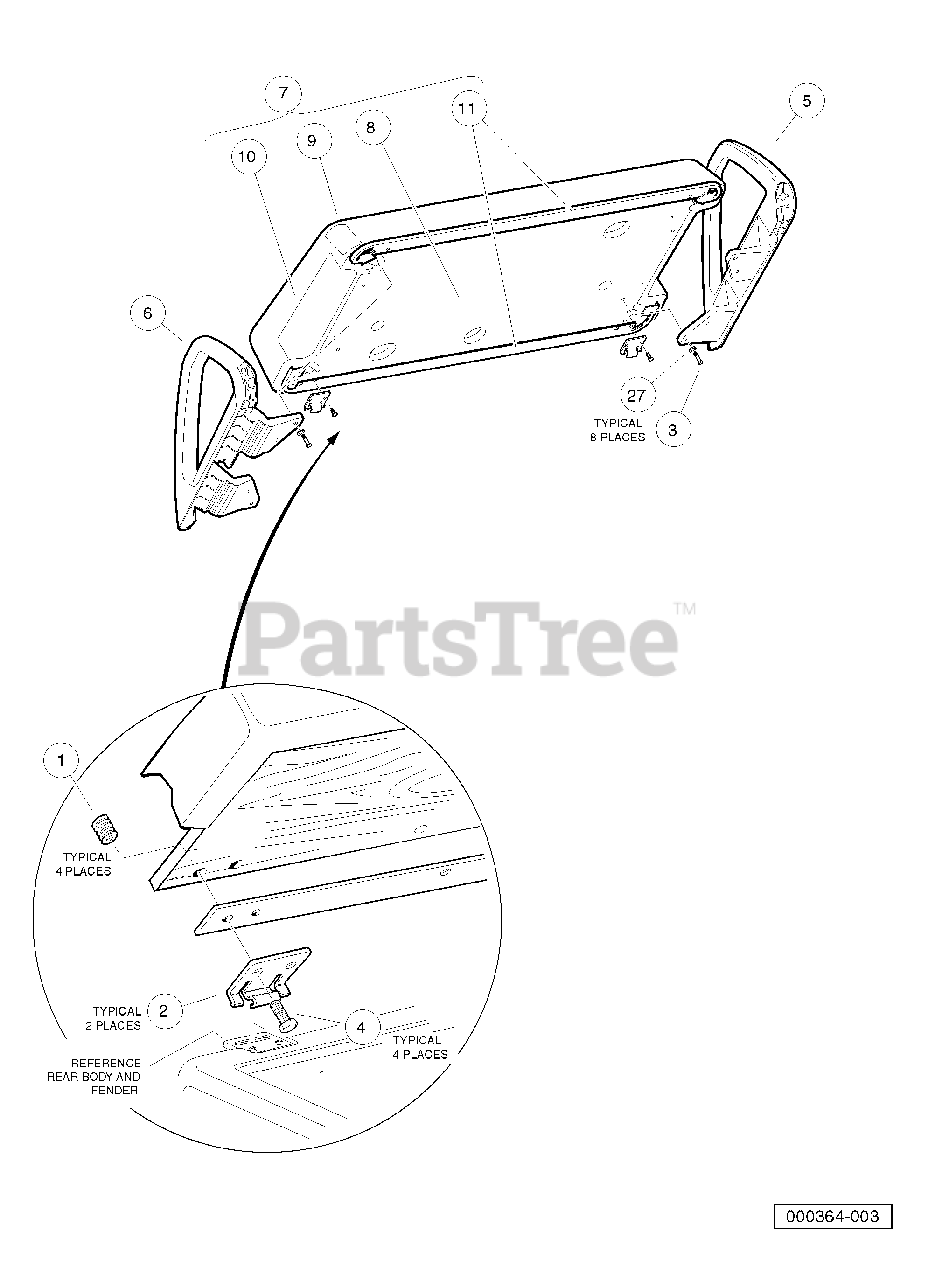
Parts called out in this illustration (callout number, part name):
1	Insert - Wood
2	Hinge Plate
3	Screw, 1/4-20 X 1.50 Hex-Head Cap
4	Screw, 1/4-20 X 0.75 Hex-Head Cap
5	Armrest, Passenger
6	Armrest, Driver
7	Seat Bottom Assembly, Buff
8	Plywood Assy
9	Vinyl Cover, Seat Bottom, Buff
10	Foam, Seat
11	Gasket, Seat
12	Seat Bottom Assembly, White
13	Plywood Assy
14	Vinyl Cover, Seat Bottom, White
15	Foam, Seat
16	Gasket, Seat
17	Seat Bottom Assembly, Black
18	Plywood Assy
19	Vinyl Cover, Seat Bottom, Black
20	Foam, Seat
21	Gasket, Seat
22	Seat Bottom Assembly, Gray
23	Plywood Assy
24	Vinyl Cover, Seat Bottom, Gray
25	Foam, Seat
26	Gasket, Seat
27	Washer, 1/4 Type A Narrow Flat
